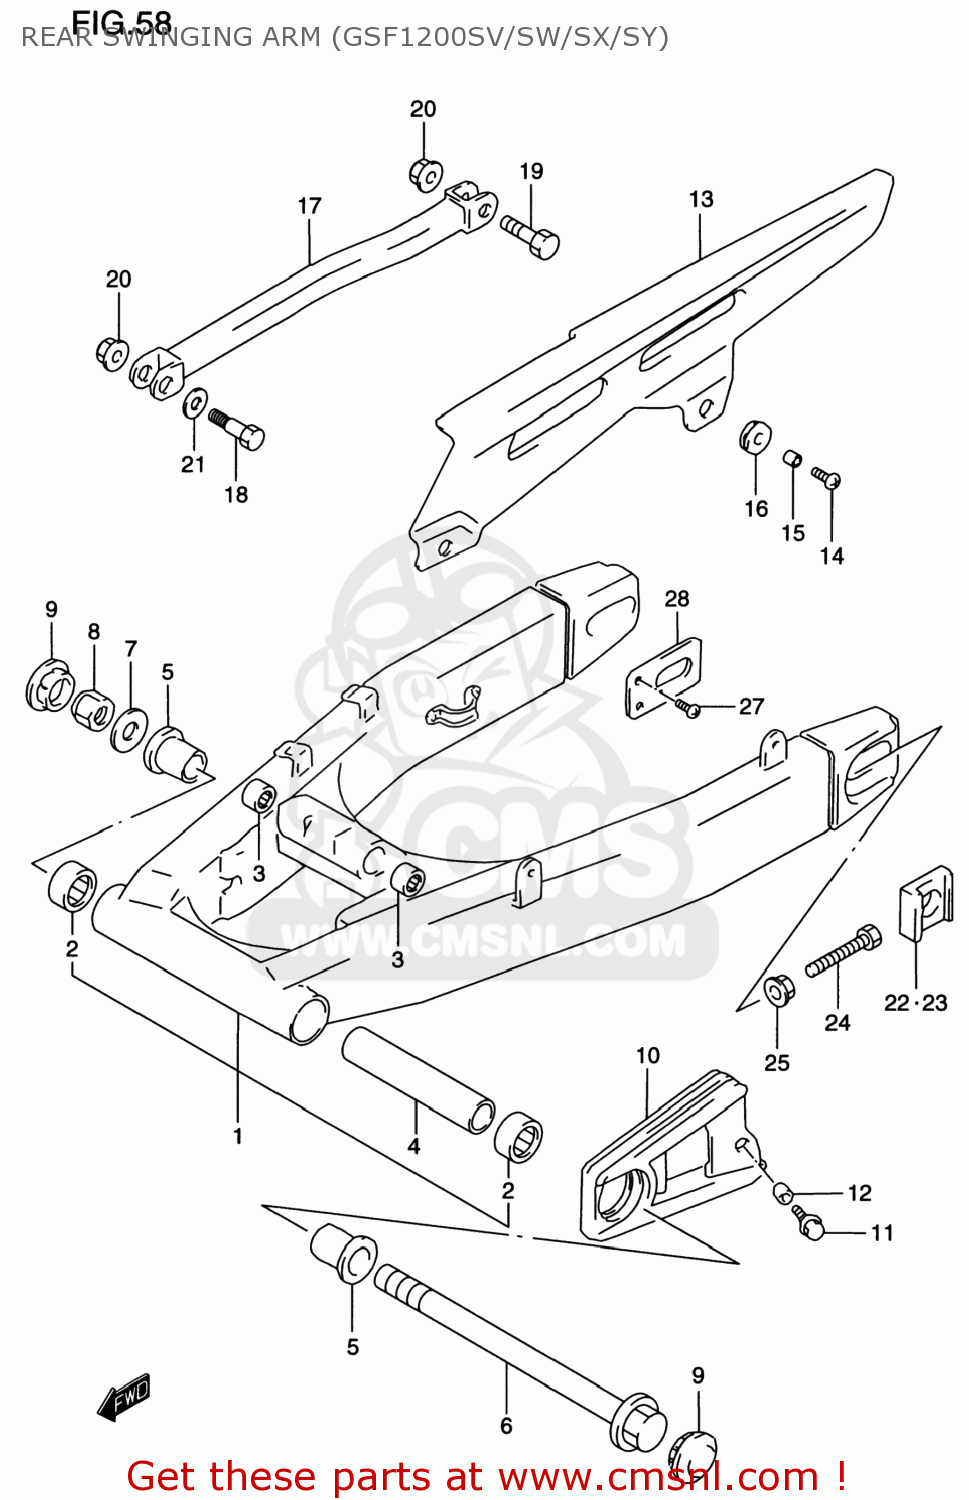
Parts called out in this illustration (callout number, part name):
1	SWINGINGARM ASSY,RR
2	BEARING(25X33X35)
3	BEARING(17X24X25)
4	SPACER,RR SWGARM PIVOT CTR
5	SPACER,RR SWGARM PIVOT BERRING
6	SHAFT,RR SWINGINGARM PIVOT
7	WASHER(18.5X28X2.6)
8	NUT
9	CAP,FRAME PIVOT
10	BUFFER,CHAIN TOUCH DEFENSE
11	BOLT(6X20)
12	SPACER(6.5X10X7)
13	CASE,CHAIN
14	SCREW (6X16)
15	SPACER(6.2X8.3X6.1)
16	CUSHION
17	TORQUELINK,RR
18	BOLT(10X39)
19	BOLT(10X37)
20	NUT
21	WASHER(12.5X20X1)
22	WASHER,CHAIN ADJUSTER
23	WASHER,CHAIN ADJUSTER
24	BOLT(8X50)
25	NUT
26	PLATE,RR SWING ARM BRKT
27	SCREW
